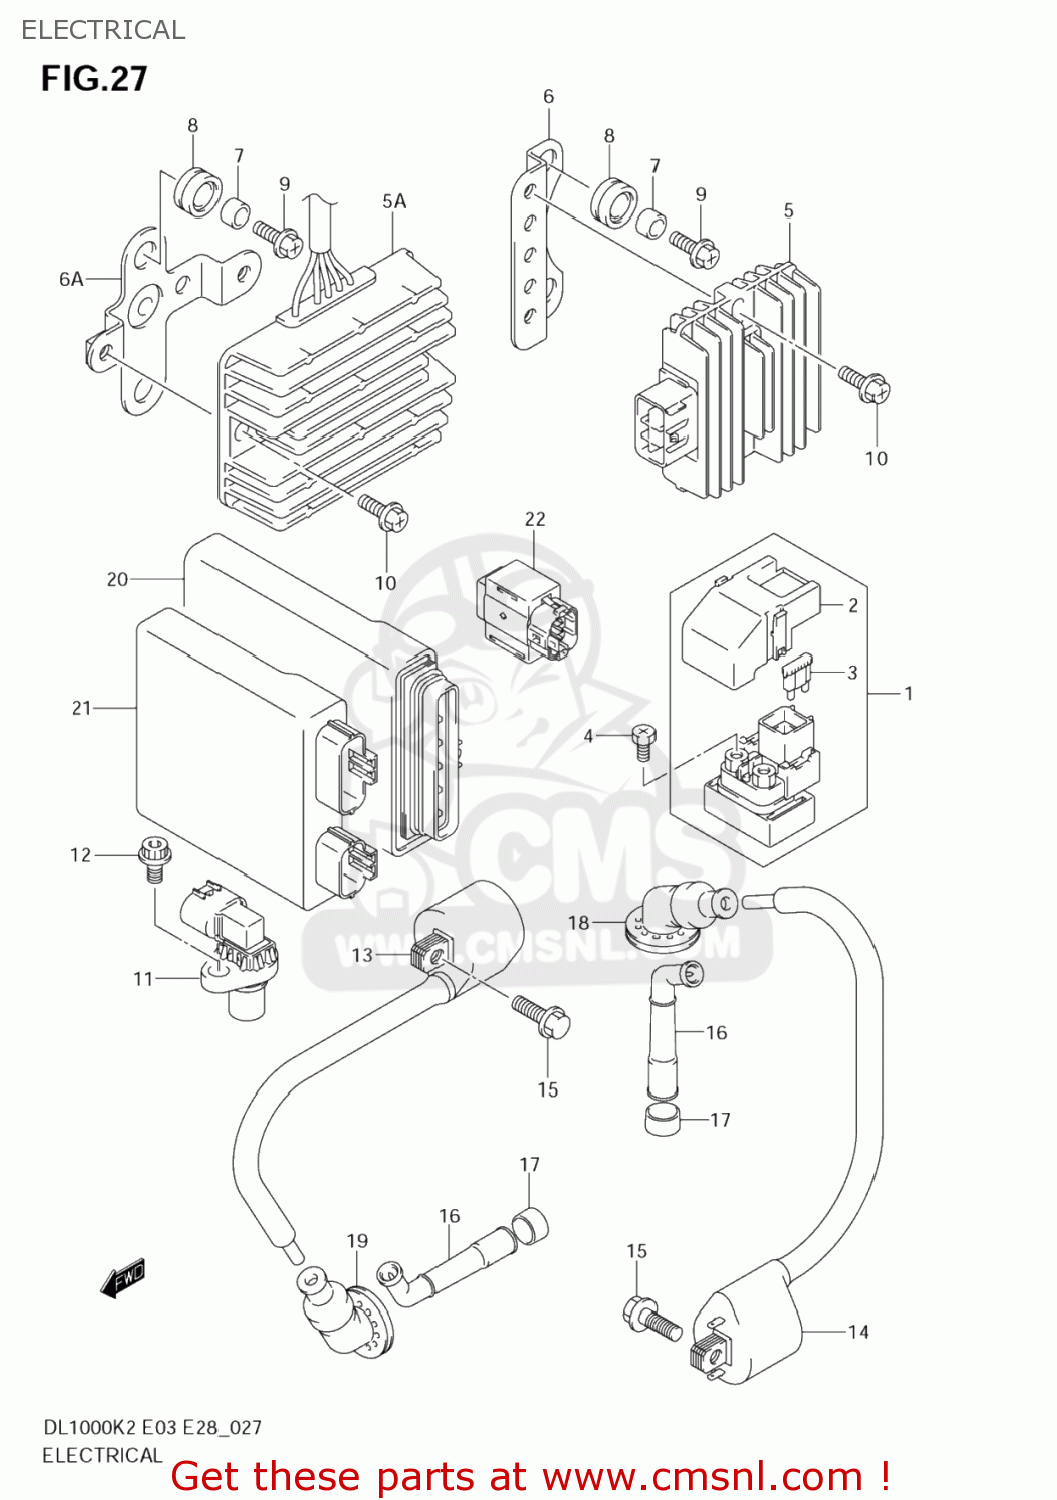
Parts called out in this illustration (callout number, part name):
1	RELAY ASSY,STARTING MOTOR
2	COVER
3	FUSE(30A)
4	SCREW(6X8)
5	RECTIFIER ASSY
5A	RECTIFIER ASSY
6	BRACKET,RECT FTG
6A	BRACKET,RECT FTG
7	SPACER(6.5X9X6.7)
8	CUSHION
9	BOLT
10	BOLT
11	SENSOR ASSY,CRANK POSITION
12	BOLT,OIL FILLE
13	COIL ASSY,IGNITION
14	COIL ASSY,IGNITION
15	SCREW
16	CAP,SPARK PLUG
17	SEAL,SPARK PLUG CAP
18	SEAL,HIGH TENSION CORD RR
19	SEAL,HIGH TENSION CORD FR
20	CONTROLER
21	CONTROL UNIT,FI
22	SENSOR ASSY,FUEL CUT
